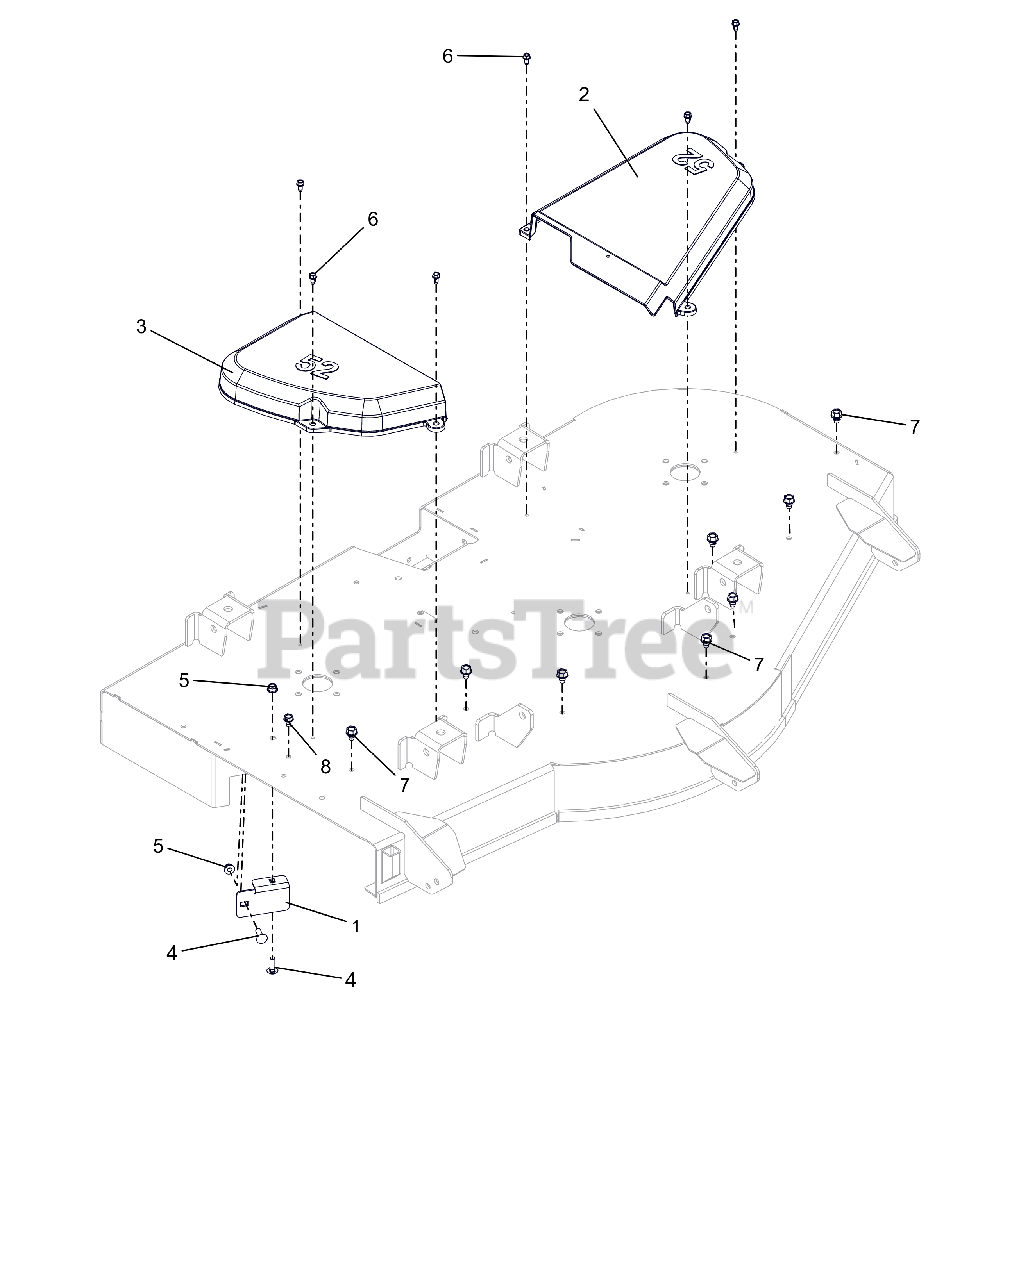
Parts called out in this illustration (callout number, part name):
1	STRIP, DEFLECTOR - 52"
2	COVER, BELT 52" LH
3	COVER, BELT 52" RIGHT
4	BLT,RHSN .31-18X1.00 G5 ZCC
5	NUT,LK-NYL-FLG .31-18 G5ZC120
6	SCR-TAP .25-20X.50 HWH ZCC
7	SCR,TAP .375-16X.50 HWH TR ZCC
8	SCR,TAP .312-18X.50 HWH TR ZCC
